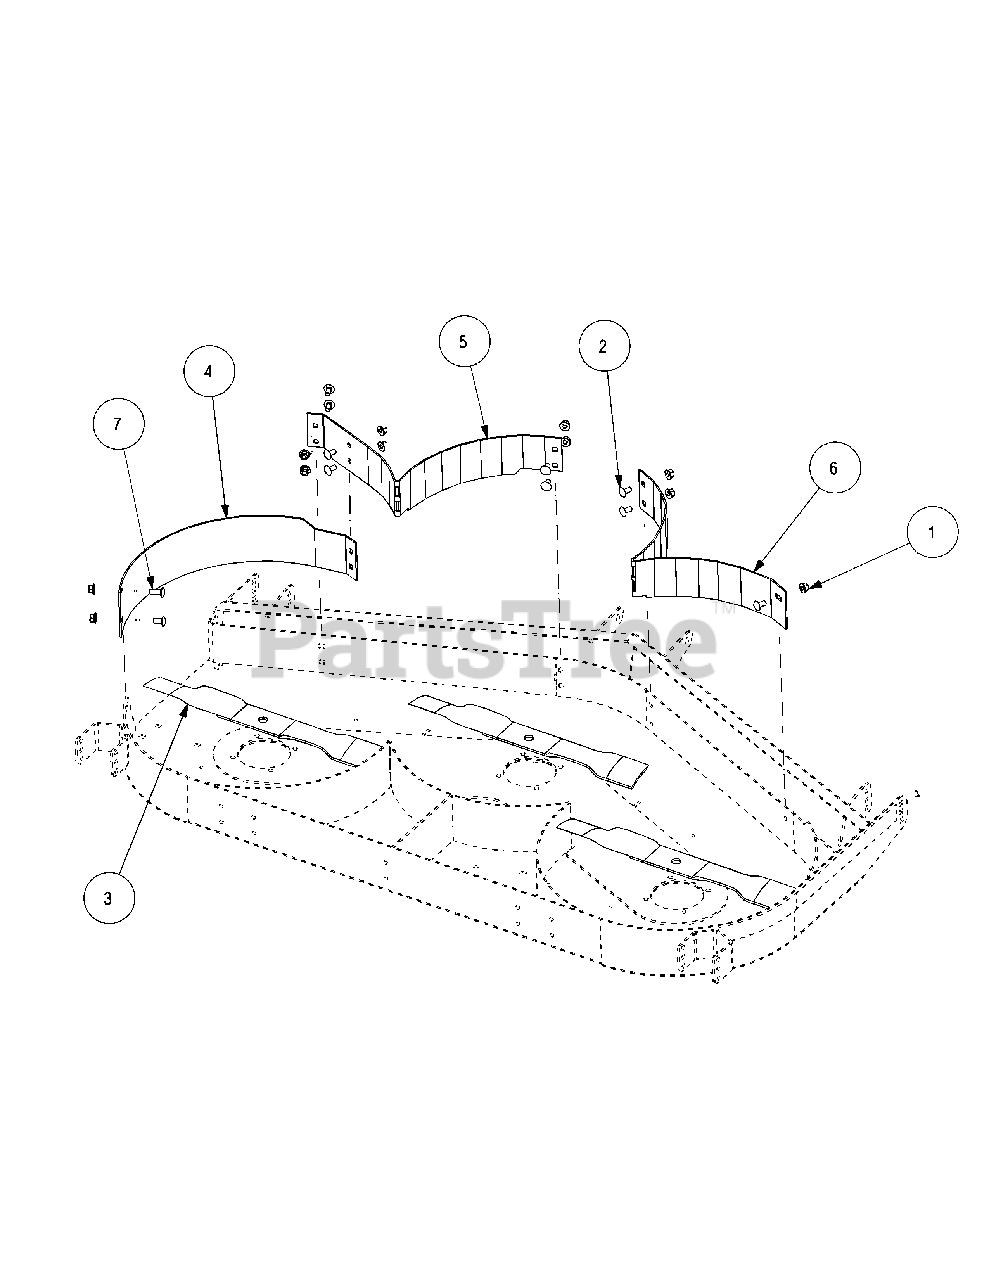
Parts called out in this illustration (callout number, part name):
1	Nut, Flange 3/8-16 Gr5
2	Bolt, Carriage 3/8-16 x .75
3	Blade:21" Mulch
4	Baffle, Mulch RH
5	Baffle, Mulch Center
6	Baffle, Mulch LH
7	Bolt, Carriage 3/8-16 Gr 5
